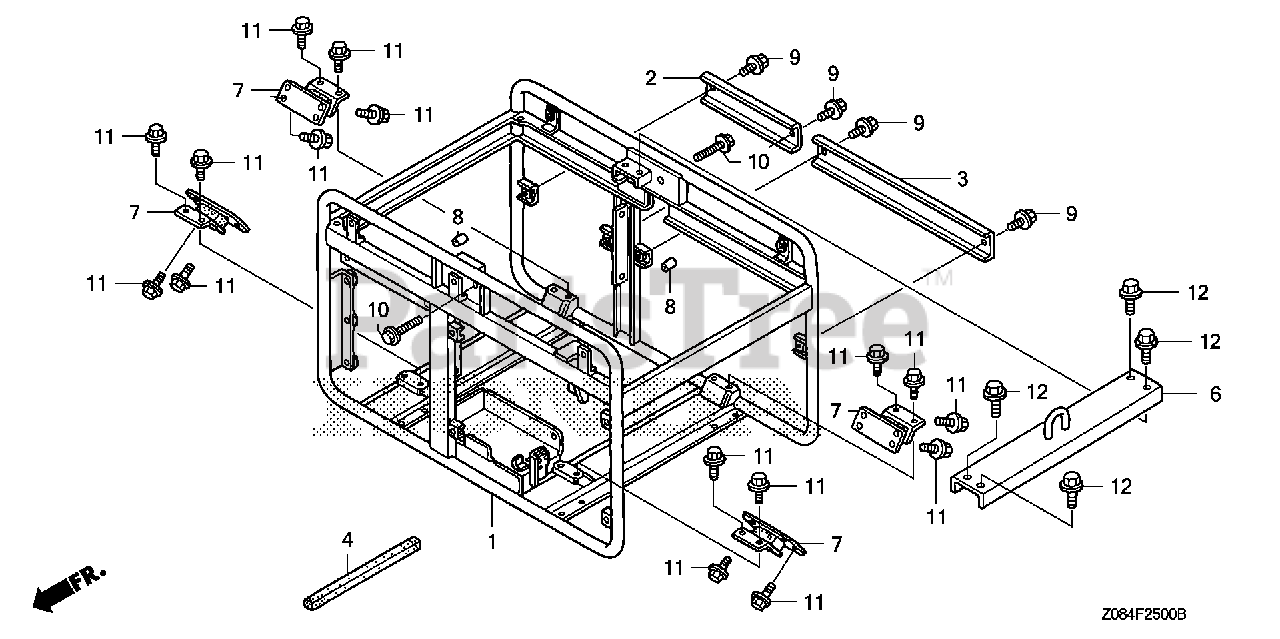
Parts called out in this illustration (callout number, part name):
1	FRAME *NH105* (MAT BLACK)
2	CHANNEL, RR. *NH105* (A) (MAT BLACK)
3	CHANNEL, RR. *NH105* (B) (MAT BLACK)
4	SEAL, COVER (UPPER)
6	BEAM *NH105* (MAT BLACK)
7	RUBBER, GENERATOR (LOWER)
8	COLLAR, SPACER
9	BOLT, FLANGE (6X12)
10	BOLT, FLANGE (6X30)
11	BOLT, FLANGE (8X16)
12	BOLT, FLANGE (12X25)
